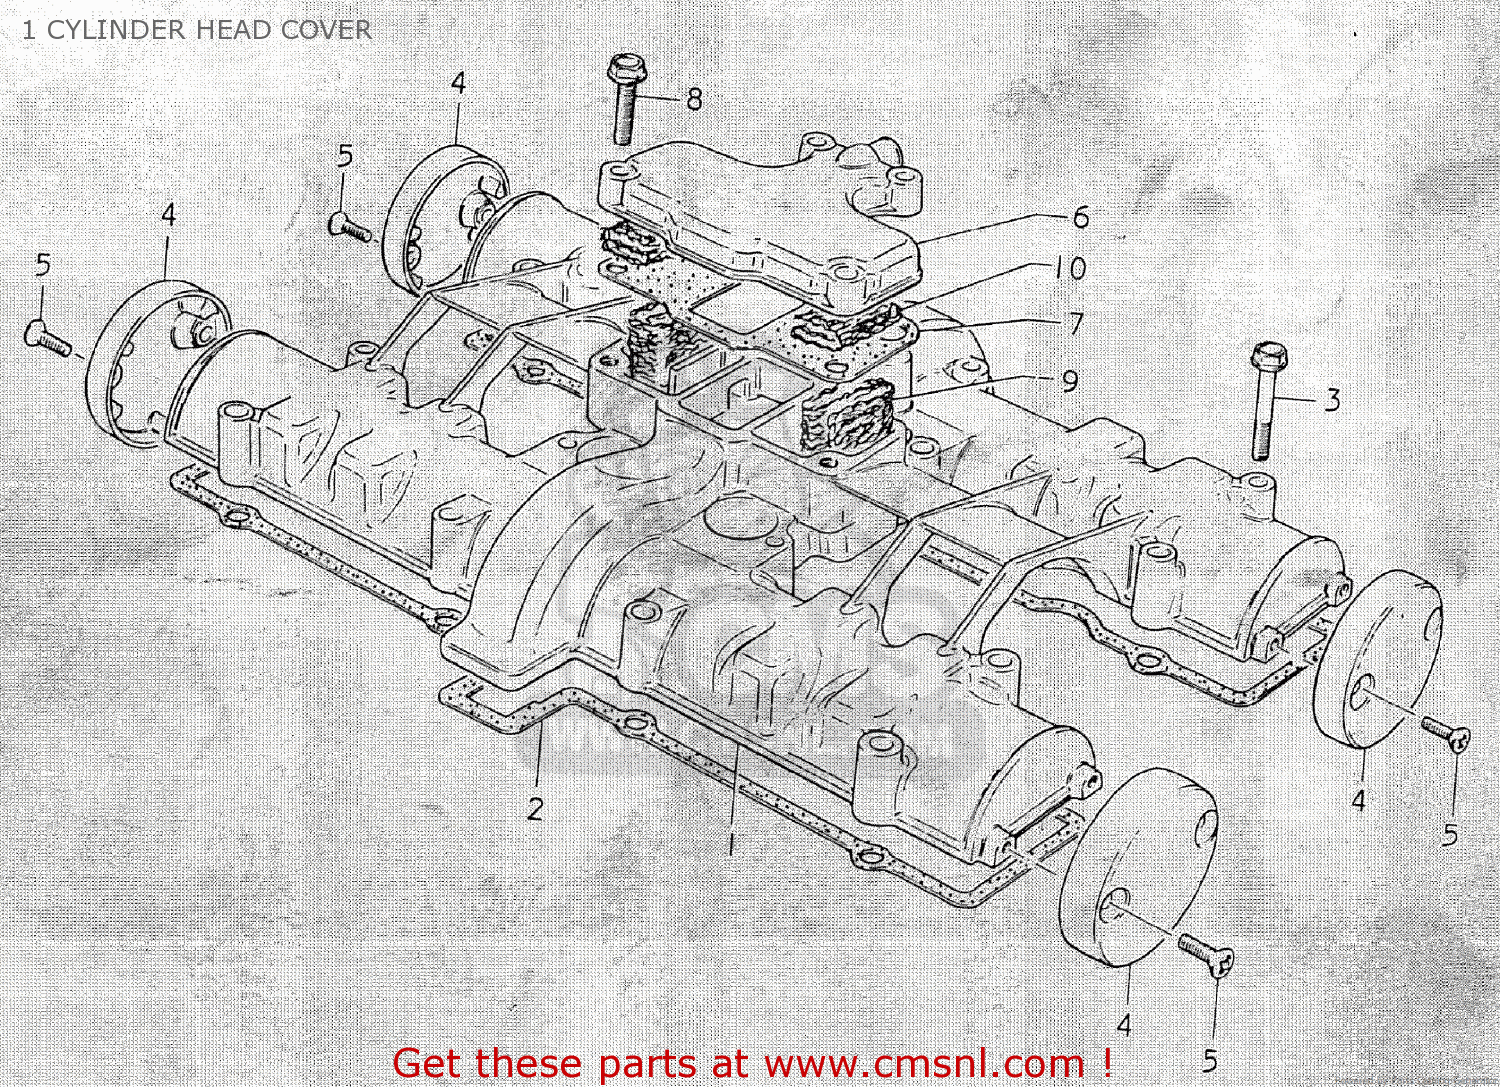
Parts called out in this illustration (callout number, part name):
1	COVER,CYLINDER HEAD
2	GASKET,CYLINDER HEAD COVER (MCA)
3	BOLT
4	CAP,CYLINDER HEAD COVER
5	SCREW
6	COVER,BREATHER
7	GASKET (MCA)
8	BOLT
9	COVER,BREATHER
10	SEPARATOR,OIL BREATHER
